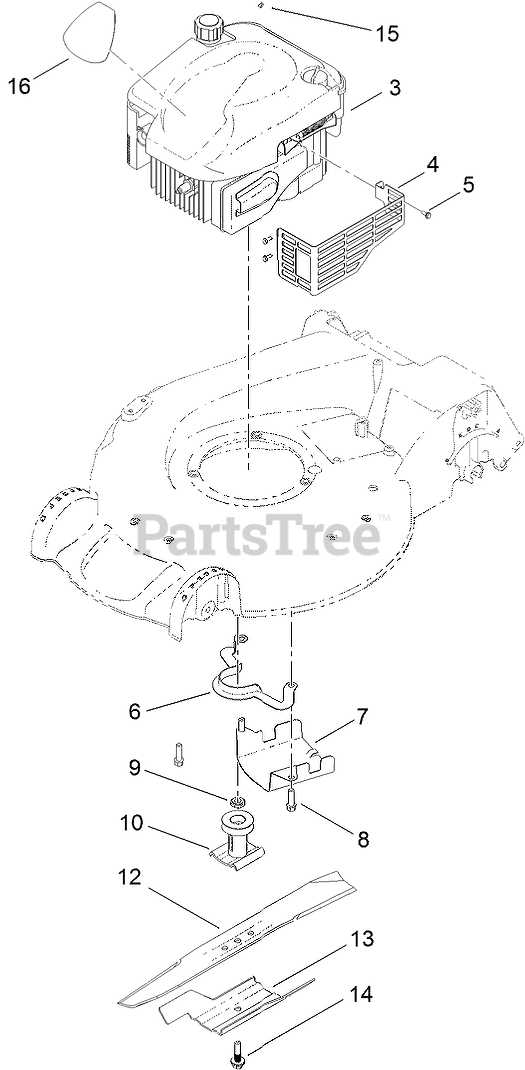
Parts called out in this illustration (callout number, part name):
4	SHIELD-MUFFLER
5	SCREW-TAPTITE
6	GUIDE-BELT
7	SHIELD-GRASS
8	SCREW-TAPTITE
9	Spacer-Driver
10	DRIVER-BLADE
12	BLADE-RECYCLING
13	Accelerator-Blade
14	BOLT-BLADE
15	STOP-ROPE
16	DECAL-SHROUD
